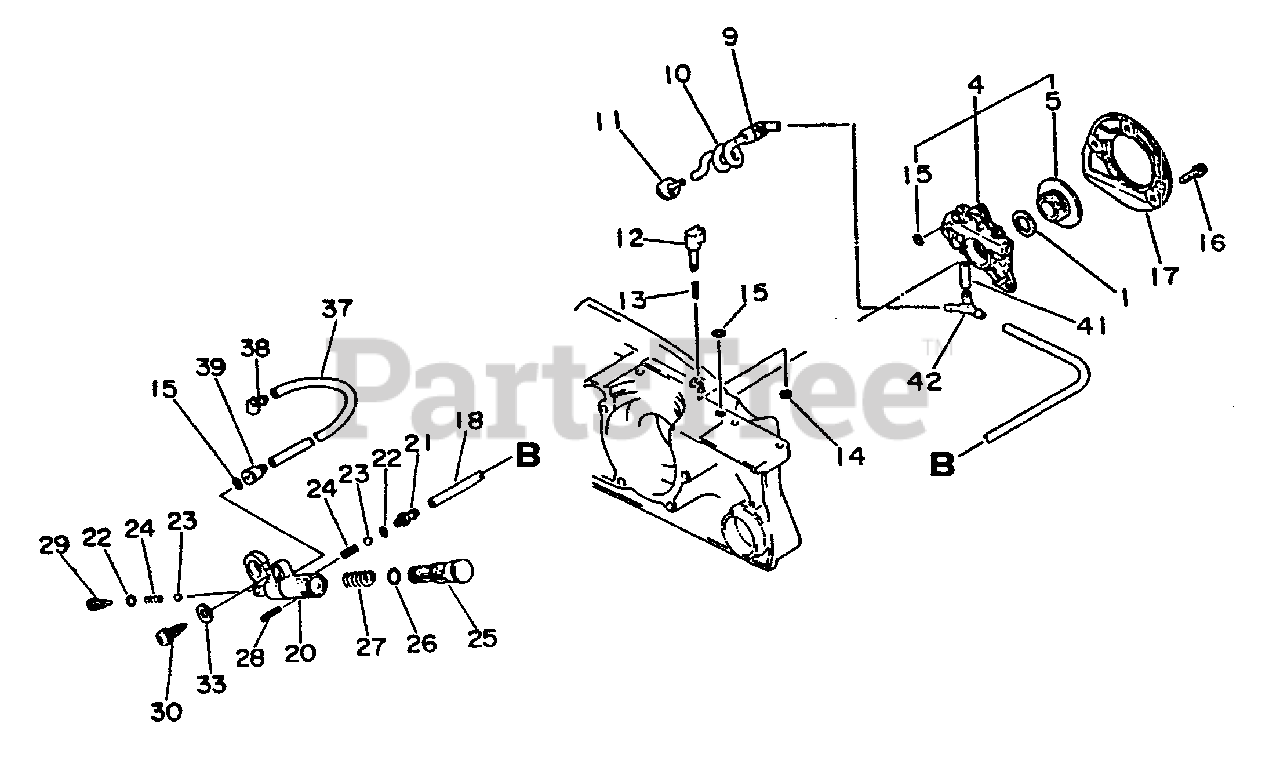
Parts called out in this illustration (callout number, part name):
4	AUTO-OILER ASSY
5	WHEEL, WORM
10	PIPE, OIL
11	FILTER, OIL
14	E-RING 3
15	O-RING 3
16	SCREW - 4×14
17	COVER, OIL PUMP - ORANGE
18	PIPE, FUEL 3×6×200
20	BODY, OIL PUMP
21	CONNECTOR, PIPE
23	VALVE, BALL
24	SPRING, VALVE
25	PISTON, OIL PUMP - BLACK
26	O-RING 7 MM
28	PIN, SPRING 2×16
29	ADAPTOR, OIL PUMP
30	SCREW - 5×20
33	WASHER 5.5×12×0.8
37	PIPE 3×6×125 BLACK
38	CONNECTOR, PIPE
39	CONNECTOR, PIPE
41	PIPE, OIL 3×6×20
42	CONNECTOR, PIPE
